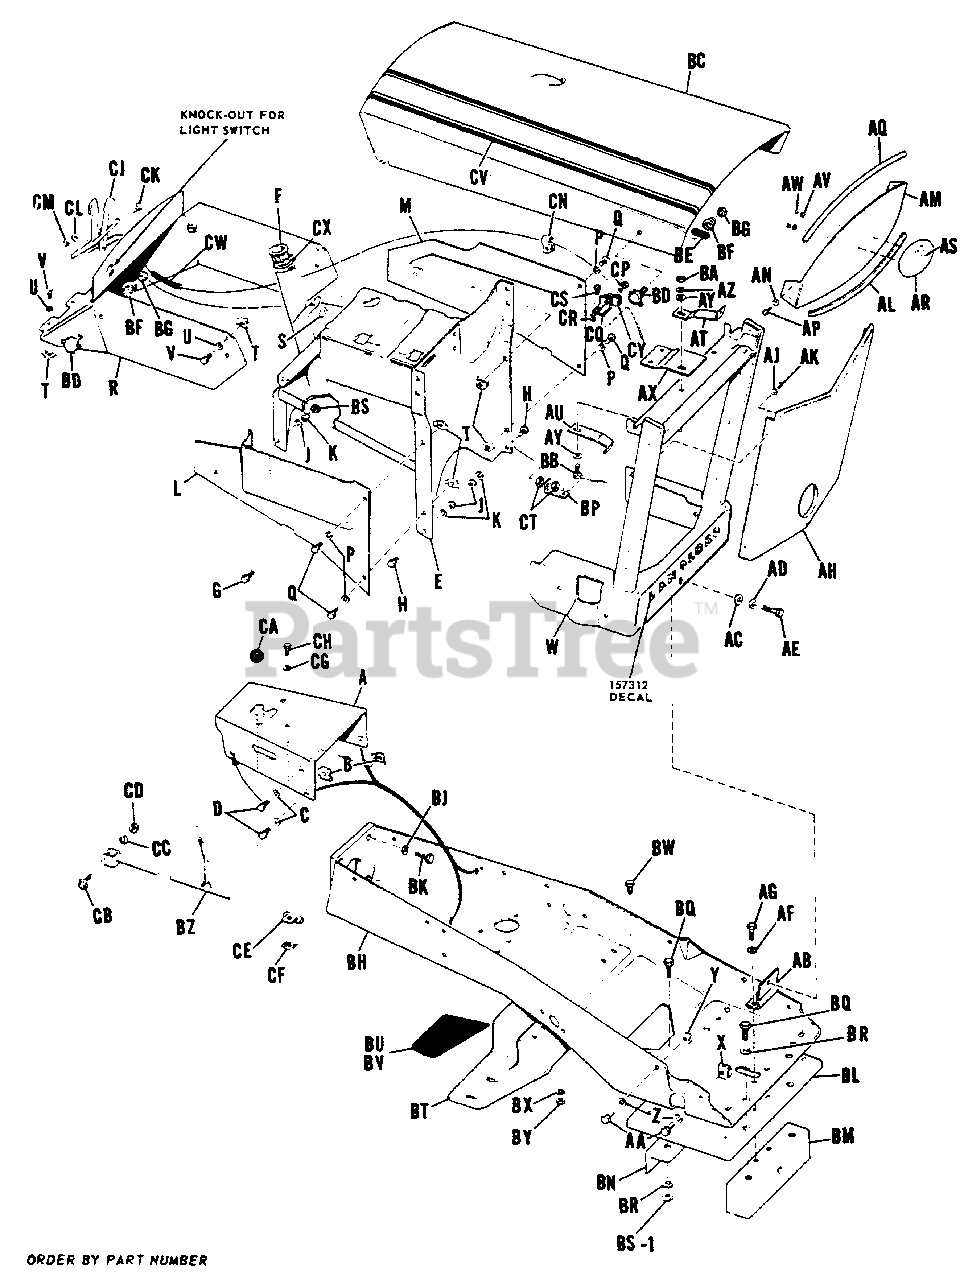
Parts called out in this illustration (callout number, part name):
A	Frame Cover
B	Retainer Nut
C	Lock Washer, 1/4"
D	Hex Capscrew, 1/4"-20 x 5/8" lg.
E	Support Assembly, Fuel Tank & Steering Post
F	Bushing, Steering
G	Hex Capscrew, 5/16"-18 x 1-1/4" lg.
H	Hex Capscrew, 5/16"-18 x 5/8" lg.
J	Hex Nut, Full, 5/16"-18
K	Lock Washer, 5/16"
L	Panel, R.H. Side
M	Panel, L.H. Side
P	Lock Washer, 1/4
Q	Hex Capscrew, 1/4"-20 x 5/8"
R	Dash Assembly
S	Nut, Flange, "Whiz-Lock", 5/16"-18
T	Nut Retainer
U	Lock Washer, 1/4"
V	Hex Capscrew, 1/4"-20 x 5/8" lg. Grade 5
W	Cover & Tube Assembly (To Replace Broken Ear Use 157385 Brkt.)
X	Nut Retainer (Front)
Y	Nut Retainer (Rear)
Z	Lock Washer, 5/16"
AA	Hex Capscrew, 5/16"-18 x 3/4" lg. Grade 5
AB	Bracket Assembly
AC	Plain Washer, 5/16"
AD	Lock Washer, 5/16"
AE	Hex Capscrew, 5/16"-18 x 1-1/4" lg.
AF	Lock Washer, 5/16"
AG	Hex Capscrew, 5/16"-18 x 1-1/2" lg.
AH	Front Grille
AJ	Plain Washer, 3/16
AK	Screw, Self-Tap, Recessed Hex Hd., #10 Dia. x 1/2" lg.
AL	Trim, Lower Grille
AM	Grille, Top
AN	Plain Washer, 3/16"
AP	Self-Tap, Recessed Hex Hd., #10 Dia. x 1/2" lg.
AQ	Trim, Upper Grille
AR	Support Assembly, Emblem
AS	Film, Front Emblem
AT	Brace, Upper Grille (Top)
AU	Brace, Upper Grille (Bottom)
AV	Lock Washer, #12
AW	Nut, Full, Hex, #10-24
AX	Bracket, Grille (157480 for 399 & 400)
AY	Plain Washer, 1/4"
AZ	Lock Washer, 1/4"
BA	Nut, Full, Hex, 1/4"-20
BB	Hex Capscrew, 1/4'-20 x 1" lg.
BD	Tee Handle Assy.
BF	Spring, Conical
BG	Lock Nut, Full, Hex, 5/16"-18
BH	Frame Assembly
BJ	Lock Washer, 7/16"
BK	Hex Capscrew, 7/16-14 x 1-1/2"
BL	Weight, Base
BN	Angle, Frame, Rear
BQ	Hex Capscrew, 7/16" 20 x 1-1/2" lg.
BR	Lock Washer, 7/16"
BS	Hex Locknut, 5/16"-18
BS	Film, Decorative
